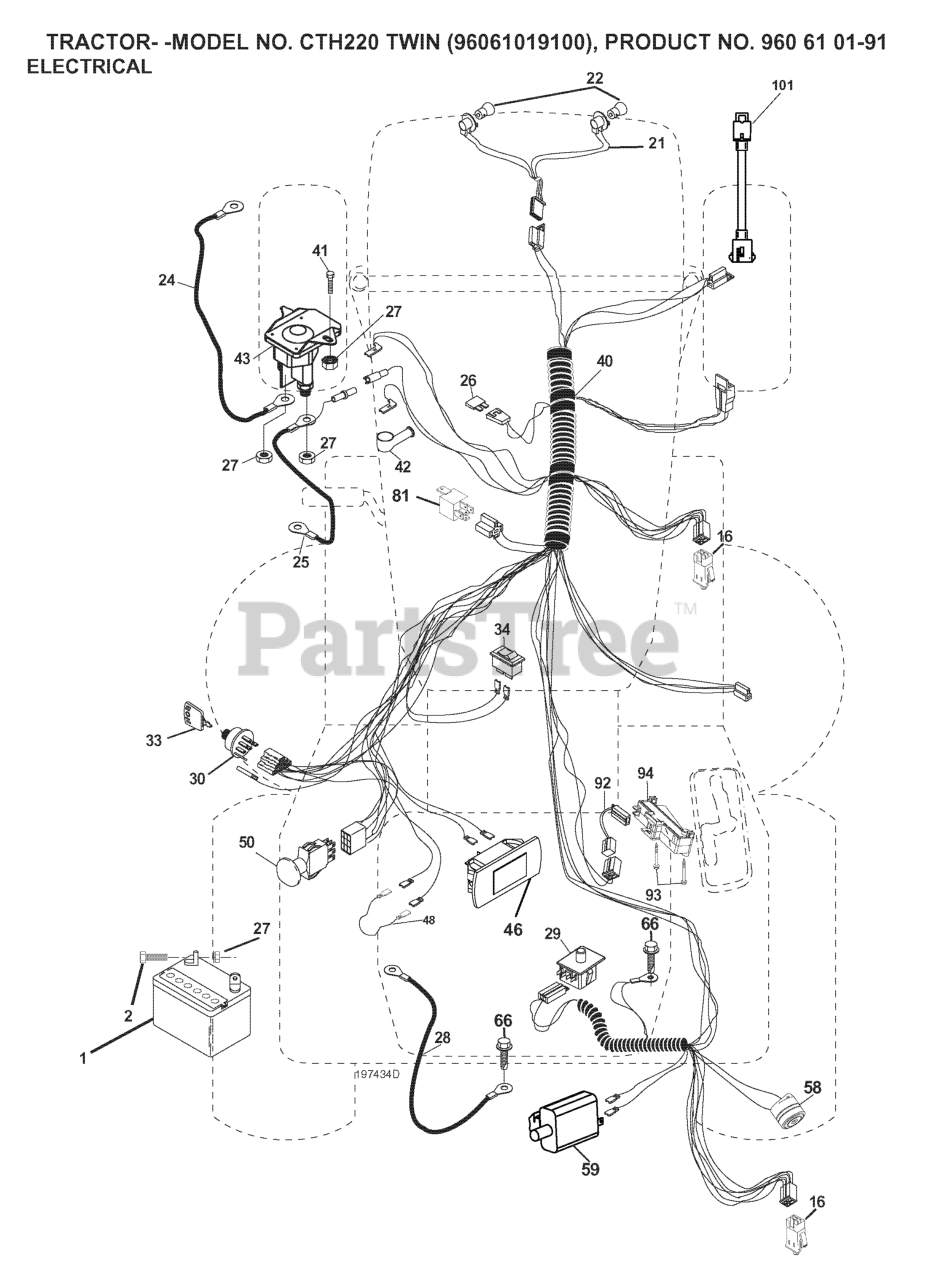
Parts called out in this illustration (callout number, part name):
1	BATTERY 12V .35 AMP
2	BOLT.HEX.1/4.X.3/4.DICHROMATE
16	SWITCH INTERLOOK PUSH-IN
21	HARNESS ASSY LIGHT
24	CABLE.BATTERY.6GA.16"RED
25	CABLE BATTERY
26	FUSE 20AMP
27	NUT
28	CABLE GROUND
29	SWITCH.SEAT.DP W/RAMPS
30	SWITCH.IGN.DELTA.W.LGH.ROS
33	KEY MLD GEN DELTA
40	RP HARNESS.IGN.ELECT.REG.CRD
41	BOLT
42	TERMINAL COVER
43	SOLENOID.W/BRASS.PLUNGER
46	RP.GUAGE.SRVCMNDR.HRMTR.
48	ADAPTER.AMMETER
50	RP.PTO.SWITCH.8 TERMINAL.BLACK
58	BUZZER
59	.WITCH.FULL BAGGER.INDICATOR
81	RELAY.ASSY.T
92	HARNESS.PIGTAIL.CONSLE
93	SCREW.PLASTITE
94	MODULE.REVERSE.ROS
101	PIGTAIL.MATNLK.NEW.HAR
